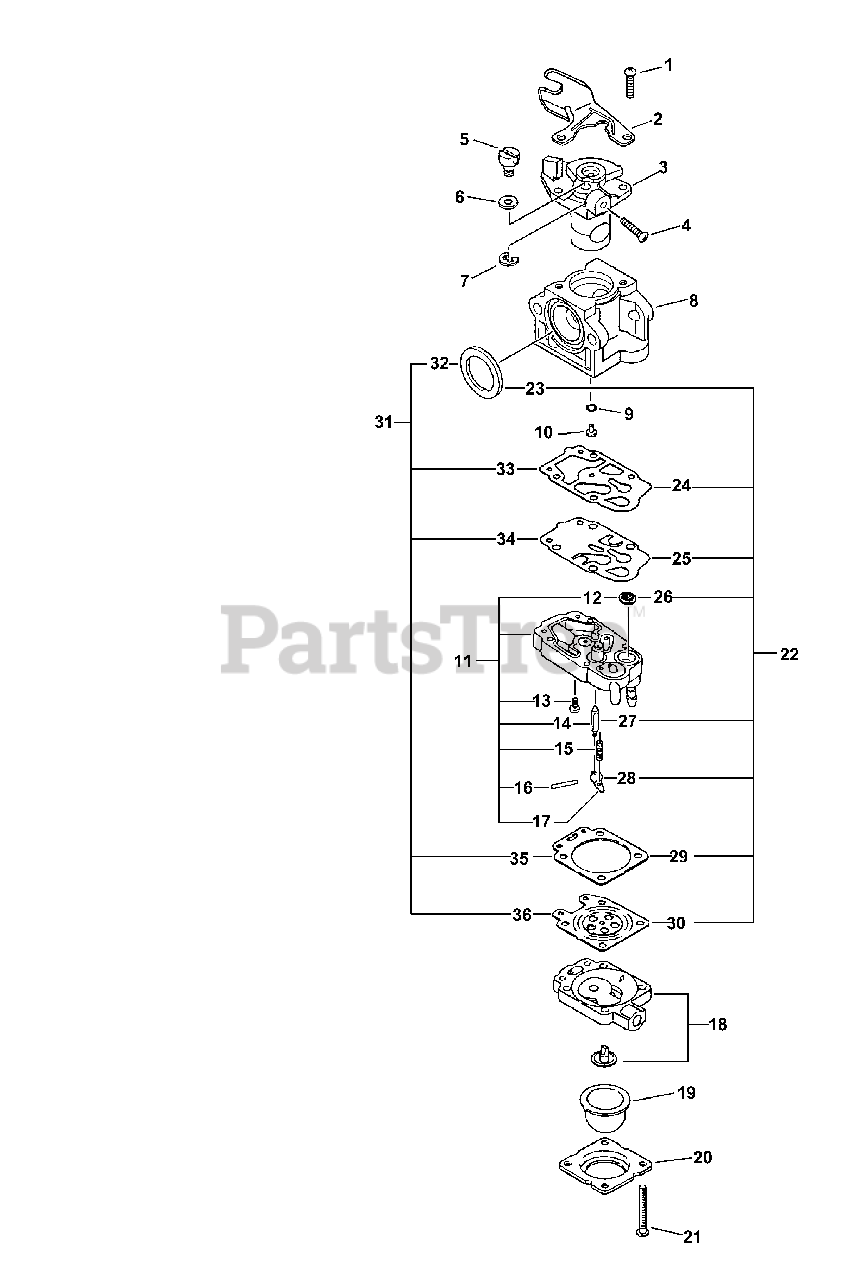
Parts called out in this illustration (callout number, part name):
2	BRACKET, THROTTLE CABLE
3	THROTTLE VALVE ASSY
8	BODY, CARBURETOR
10	JET, MAIN
11	BODY ASSY, PUMP
12	STRAINER
14	VALVE, INLET NEEDLE
15	SPRING, METERING LEVER
16	PIN, METERING LEVER
17	LEVER, METERING
18	BODY ASSY, PURGE
19	BULB, PURGE
20	RETAINER, PURGE BULB
22	REPAIR KIT, CARBURETOR
23	SEAL
24	GASKET, PUMP
25	DIAPHRAGM, PUMP
26	STRAINER
27	VALVE, INLET NEEDLE
28	LEVER, METERING
29	GASKET, METERING
30	DIAPHRAGM, METERING
31	GASKET / DIAPHRAGM KIT
32	SEAL
33	GASKET, PUMP
34	DIAPHRAGM, PUMP
35	GASKET, METERING
36	DIAPHRAGM, METERING
